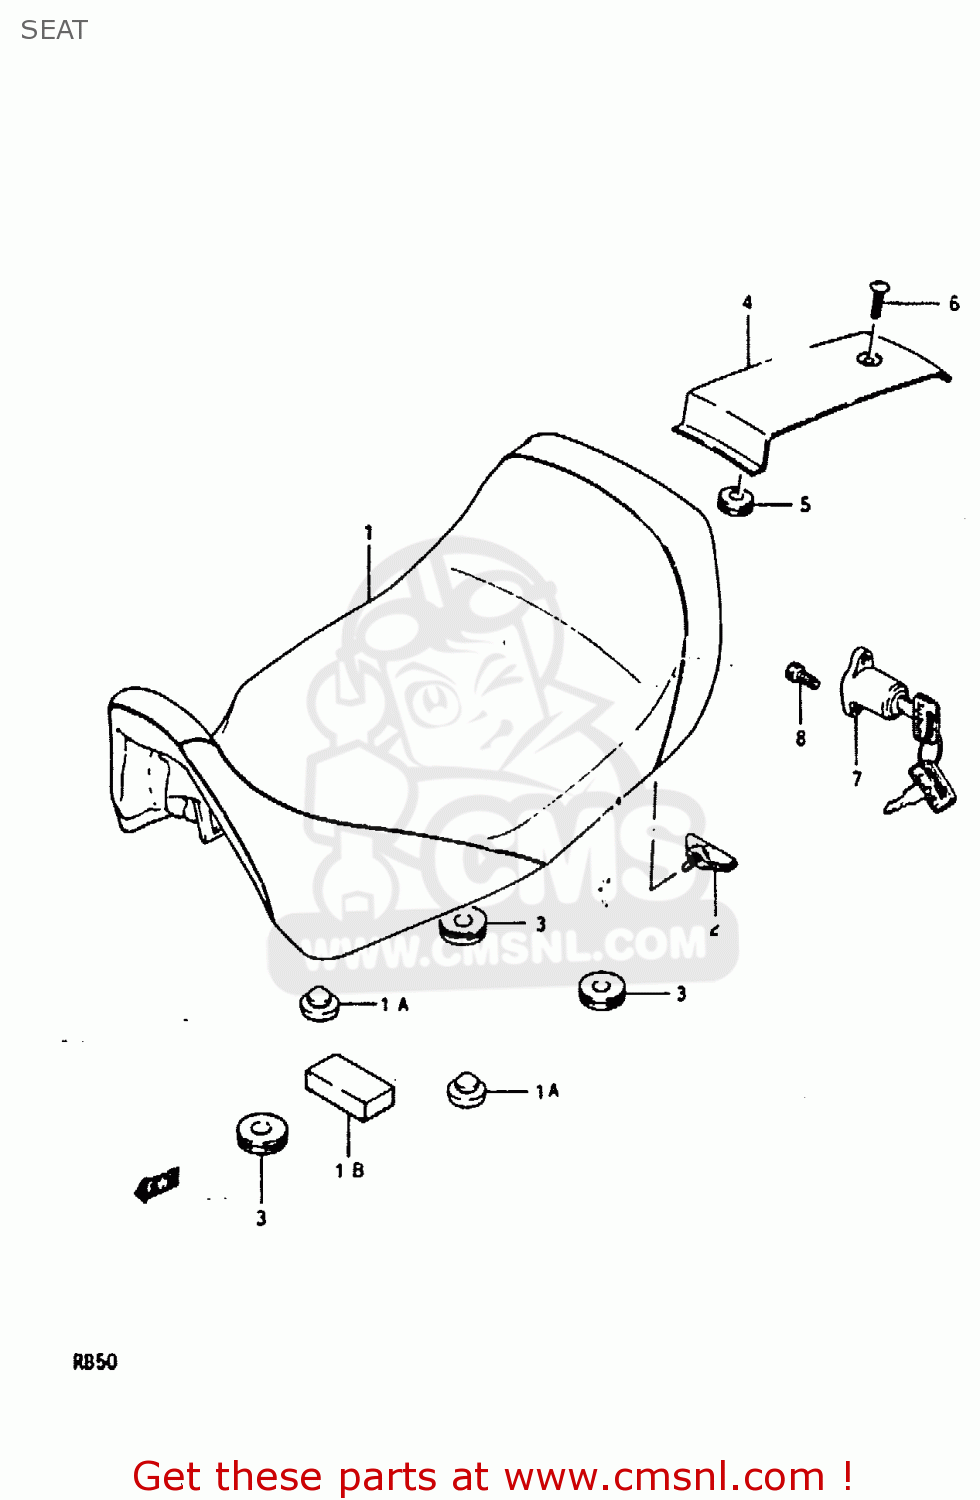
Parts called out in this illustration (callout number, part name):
1	SEAT SET
1A	CUSHION
1B	CUSHION,BATTERY STOPPER
2	BOLT
3	CUSHION
4	KAP.DUOZIT
5	CUSHION
6	SCREW (L:20)
7	LOCK SET
8	BOLT
